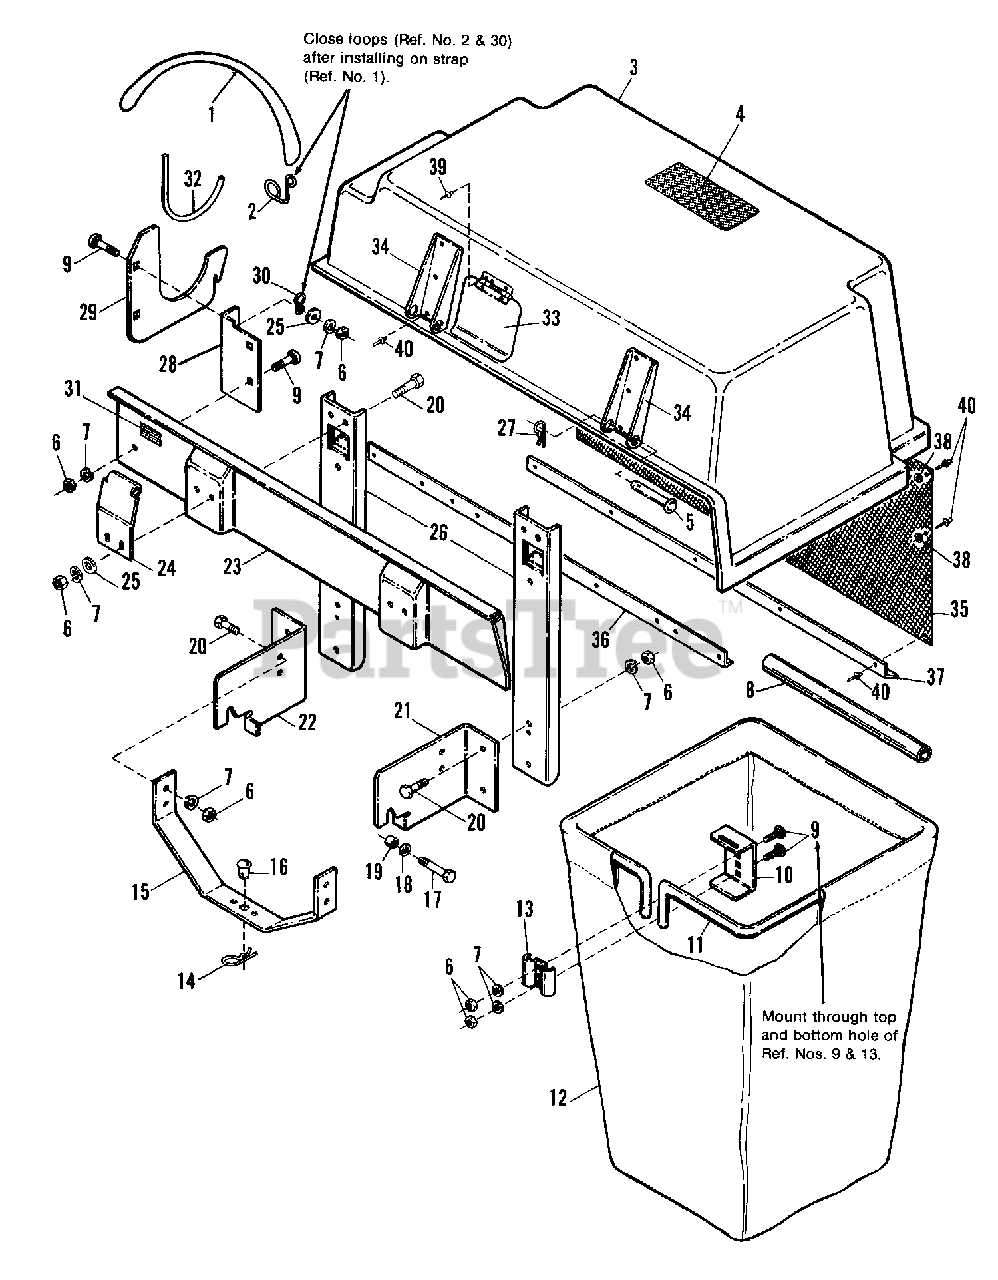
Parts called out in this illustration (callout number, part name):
2	HOOK, Strap
3	COVER ASSEMBLY (Incl. Ref. Nos. 4, 33 & 34)
4	DECAL, Warning
6	NUT, Hex, 5/16-18
7	LOCKWASHER, 5/16
9	BOLT, Carriage, 5/16-18 x 7/8 (Qty. 9 Deluxe only)
14	CLIP, Hairpin
15	BRACE, Lower
17	CAPSCREW, Hex, 3/8-16 x 1-1/4
18	WASHER, 3/8
20	CAPSCREW, Hex, 5/16-18 x 7/8
21	SUPPORT, L.H.
22	SUPPORT, R.H.
23	PLATE, Support, Cover
24	PLATE, Hinge
25	WASHER, 3/8 x 7/8
26	BRACE, Upper
27	CLIP, Hairpin
28	MOUNT, Saddle Bracket
29	BRACKET, Saddle Assembly
33	DOOR & HINGE
34	HINGE, Bracket
36	BRACKET, Front Cover
37	BRACKET, Rear Cover
38	WASHER, Rivet
